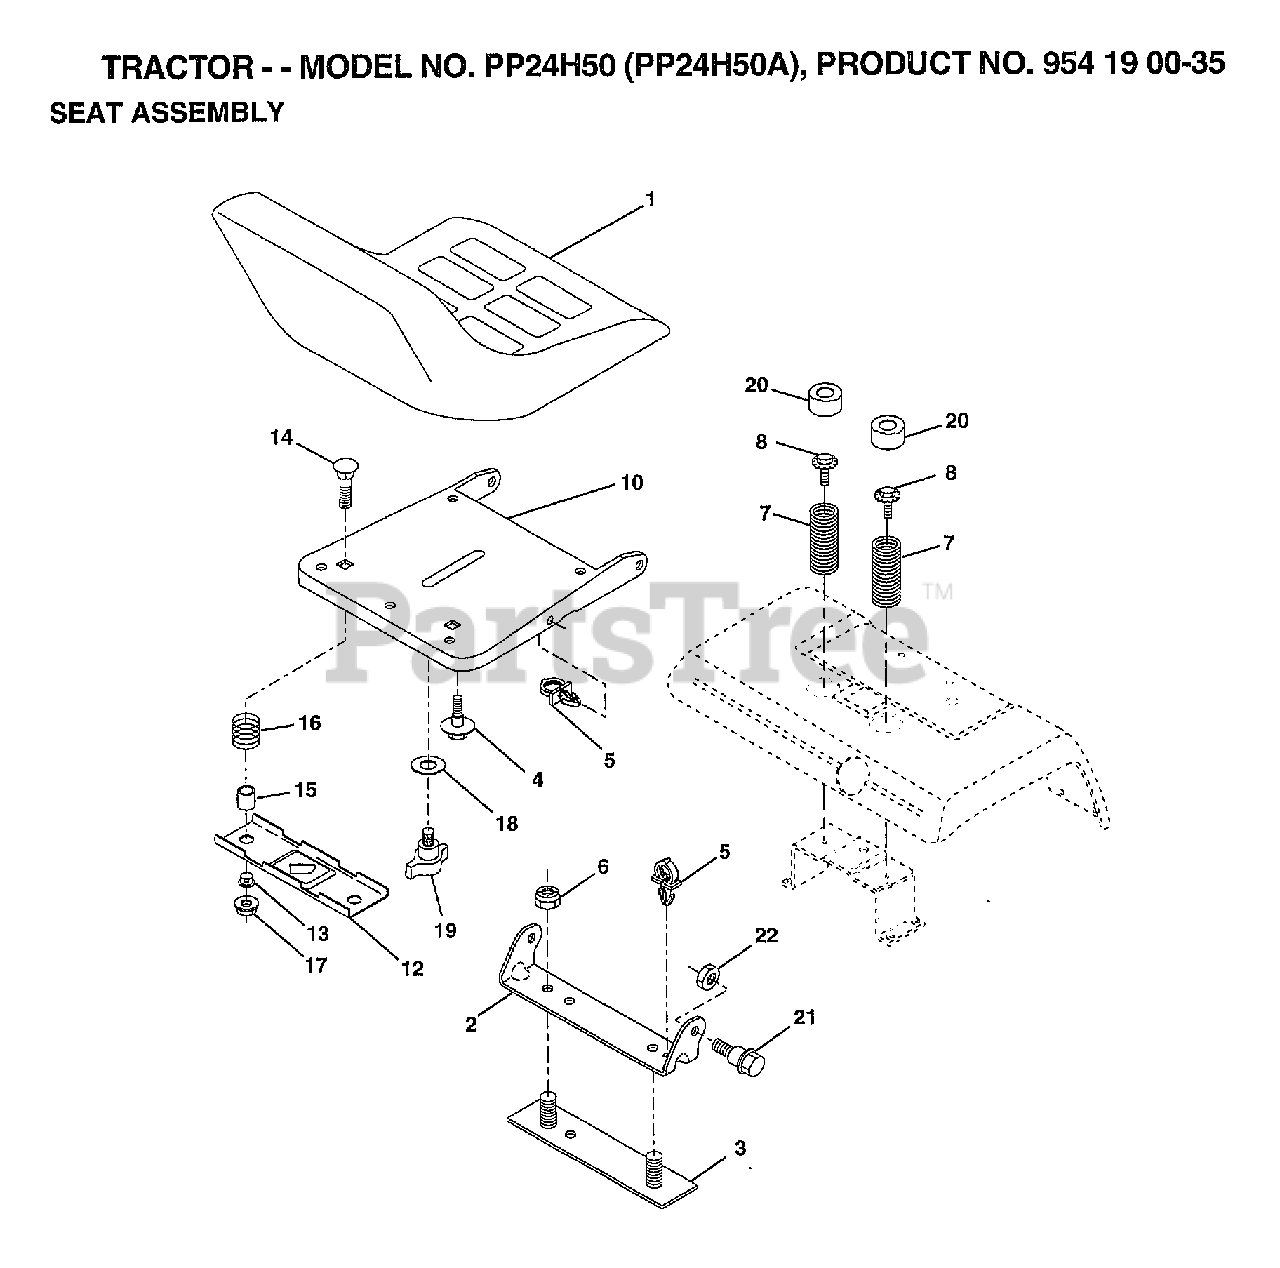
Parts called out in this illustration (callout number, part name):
2	BRACKET PVT SEAT
3	STRAP ASM FENDER
4	"BOLT,SHOULDER"
5	CLIP.PUSH-IN.HING
7	SPRING COMPRESSIO
8	BOLT.5/16-18.UNC
10	PAN-SEAT
12	BRKT SWITCH
13	BUSHING
14	BOLT-RD HD SQ NK
15	SPACER SPLIT
16	SPRING COMPRESSED
18	WASHER
19	KNOB.SEAT.ADJ.WINGNUT
20	CAP SPRING
21	"BOLT,SHOULDER"
